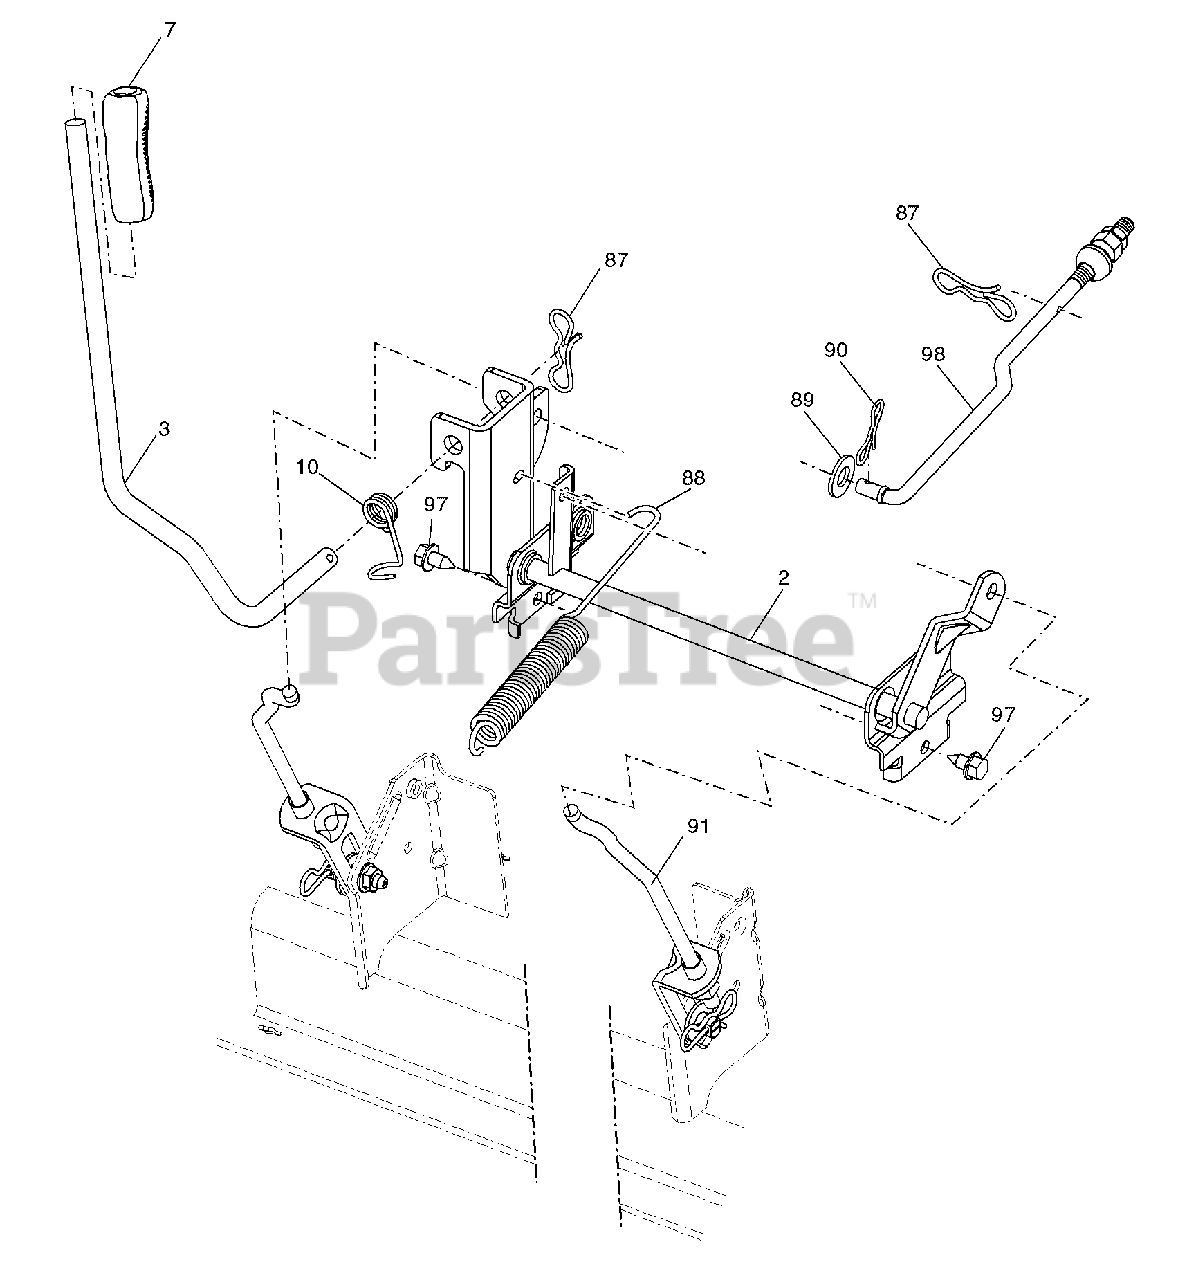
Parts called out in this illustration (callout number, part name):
2	Shaft Asm., Lift
3	Lever Asm., Lift Rh
7	Grip, Lever
10	Spring Torsion
87	Pin Cotter 7/16 Bow Tie Lock
88	Spring Lift Assist
89	Washer Clear Zinc
90	Pin Cotter 5/16 Bow Tie Lock
91	Link Lift Susp Mower Rear
97	Screw 3/8-16 x .75 Smgml Tap/ R.Z
98	Link Lift Susp. Front Mower
